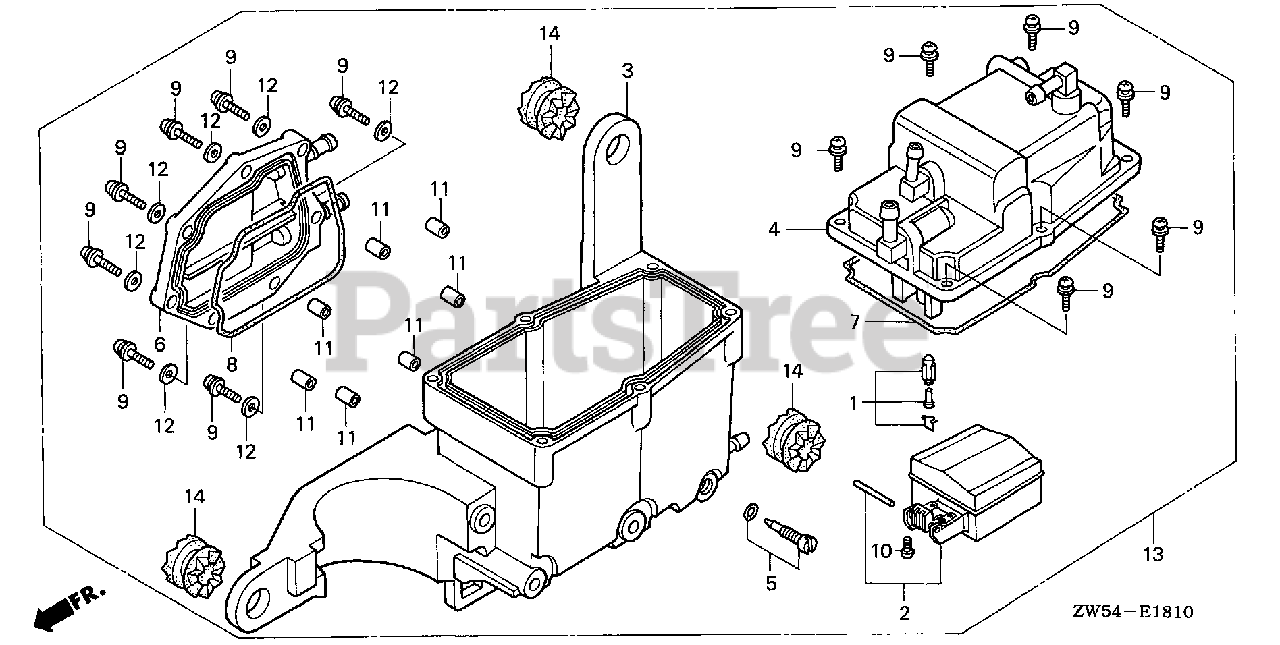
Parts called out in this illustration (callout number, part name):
1	VALVE SET, FLOAT
2	FLOAT SET
3	BODY, CHAMBER
4	COVER
5	SCREW SET, DRAIN
6	COVER, WATER JACKET
7	O-RING
8	O-RING
9	SCREW-WASHER
10	SCREW, PAN (4X8)
11	COLLAR
12	WASHER, PLAIN
13	SEPARATOR ASSY., VAPOR
14	GROMMET, VAPOR SEPARATOR
